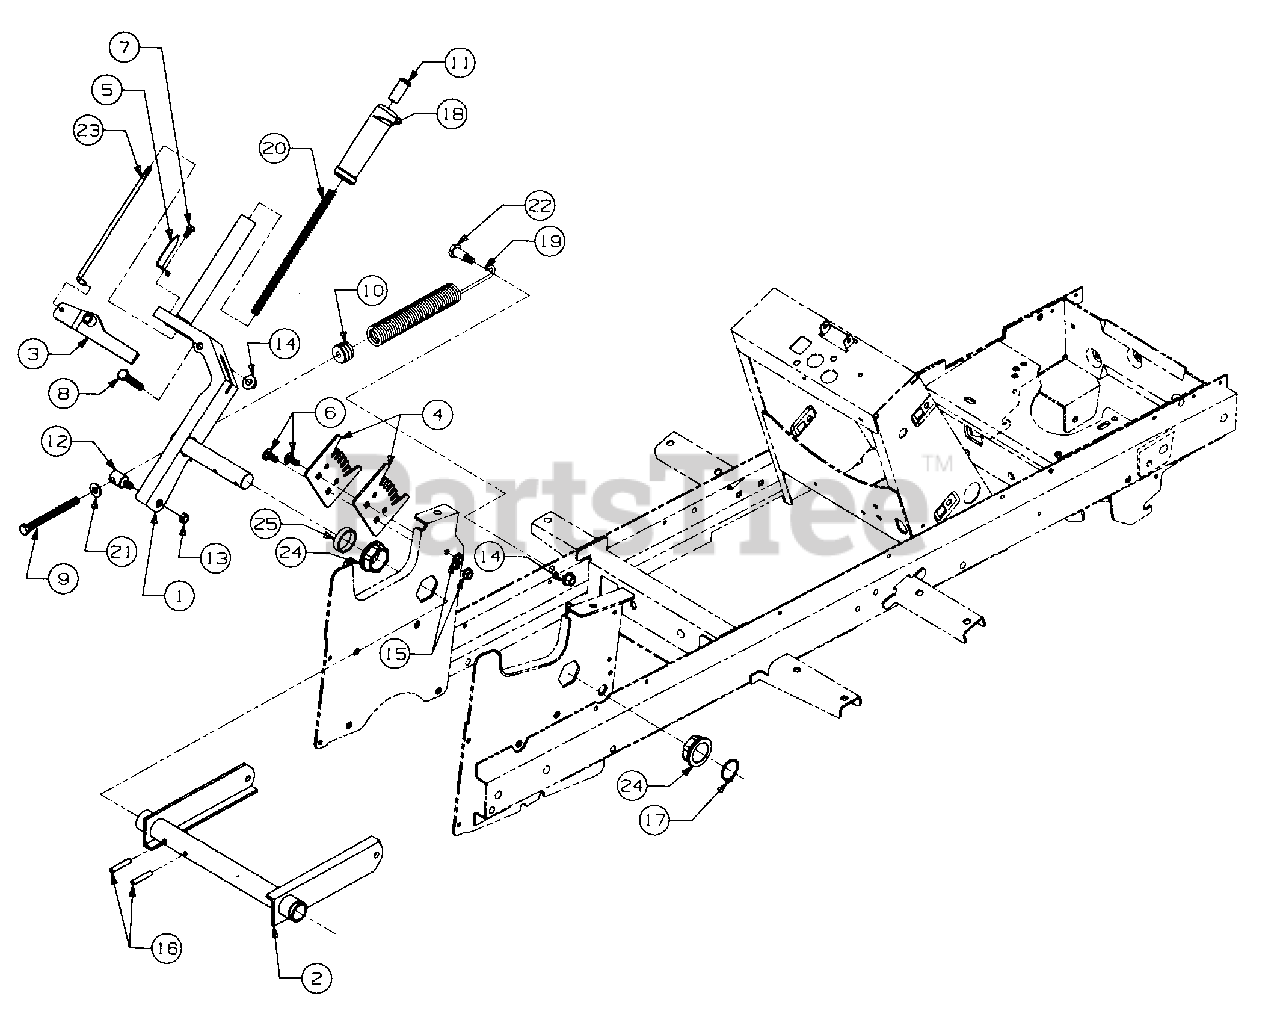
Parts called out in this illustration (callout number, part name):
3	Fork, Lift
4	Bracket, Lift Index
5	Indicator, Lift Height
6	Bolt, Carriage, 5/16-18 x .75 Lg
7	Screw, Hex Wash Tapp, 1/4 x .50 Lg
8	Screw, Hex Cap, 3/8-16 x 2.0 Lg GR5
9	Screw, Hex Cap, 3/8-16 x 4.25 Lg GR5
10	Insert, Spring
11	Button, Handle
12	Ferrule, Adjustment
13	Nut, Hex Center Lock, Jam 3/8-24
14	Nut, Hex Flanged Lock, 3/8-16
15	Nut, Hex Flanged Top Lock 5/16-18
16	Pin, Spiral Spring, 1/4 Dia x 1.50 Lg
17	Ring, Snap, 1.25 Dia Shaft
18	Grip, Lift Handle
19	Spring, Extension
20	Spring, Compression
21	Washer, Flat, .385 x .87 x .06 Thk
22	Bolt, Shoulder
23	Rod, Index
24	Bearing, Hex Flange, 1.25 ID
25	Spacer, 1.28 ID x 1.5 OD x .335 Lg
